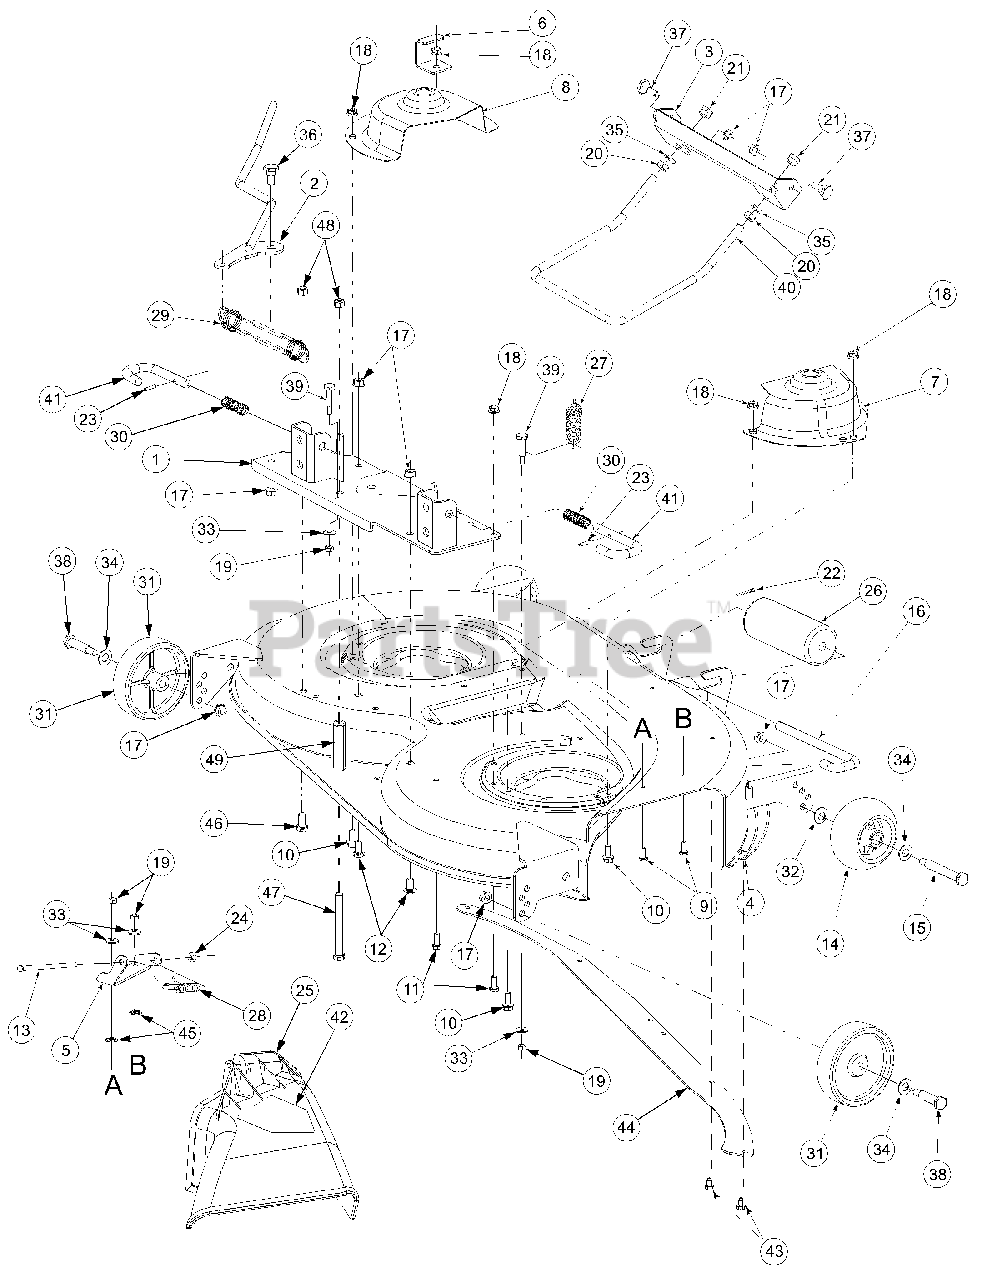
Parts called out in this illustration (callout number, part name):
4	Deck Assembly, 42"
4	Graphic, Danger Top/RH Deck
4	Graphic, Tension Lever
4	Graphic, Safety Top/LH Deck
4	Graphic, Cut
4	Graphic, 42" Cut
4	Graphic, Belt Route
5	Bracket, Hinge Mounting
9	Screw, Hex Cap, 1/4-20 x .62 GR5
10	Screw, Hx Wsh Hd Tapp, 5/16-18 x .75
11	Screw, Hex Cap, 5/16-18 x .75 GR5
12	Bolt, Carriage, 3/8-16 x .75
13	Pin, Hinge, .25 Dia x 6.75 Lg
14	Wheel, Deck w/Fitting
14	Lube, Fitting
15	Bolt, Shoulder, 1/2 x 2.5
16	Pin, Roller, 1/2 Dia x 7.31 Lg
17	Nut, Hex Flange Lock, 3/8-16
18	Nut, Hex Flange Lock, 5/16-18 GR5
19	Nut, Hex, 1/4-20
20	Nut, Hex Jam, 1/2-13 GR5
21	Nut, Hex Insert Lock, 1/2-13
22	Pin, Cotter, 3/32 x 1.25
23	Pin, Spirol Spring, 3/16 x .75
24	Cap, Speed Nut
25	Deflector Assy,
27	Spring, Extension, .88 OD x 6.12
28	Spring, Torsion
29	Spring, Extension, 1.25 OD x 8.15
30	Spring, Compression
31	Wheel, Deck, 5 in. Dia
32	Washer, Bell, .401 x .870 x .063
33	Washer, Bell, .265 x .75 x .062
34	Washer, Flat, .510 x 1.0 x .060
35	Washer, Lock, 1/2
36	Bolt, Shoulder, .498 Dia x .340 Lg
37	Bolt, Shoulder, .50 Dia x .434 Lg
38	Bolt, Shoulder, .498 Dia x 1.64 Lg
39	Bolt, Shoulder, .375 Dia x 1.16 Lg
40	Rod, Front Lift
41	Pin, Mower Support
42	Graphic, Danger
43	Screw, Self Tapping, 1/4-20 x .5
44	Skirt, Deck
45	Nut, Push, 1/4
46	Screw, Hx Cap Lock, 3/8-24 x .75 GR5
47	Screw, Hex Cap, 3.8-24 x 3.75 GR5
48	Nut, Hex Insert Lock, 3/8-24
